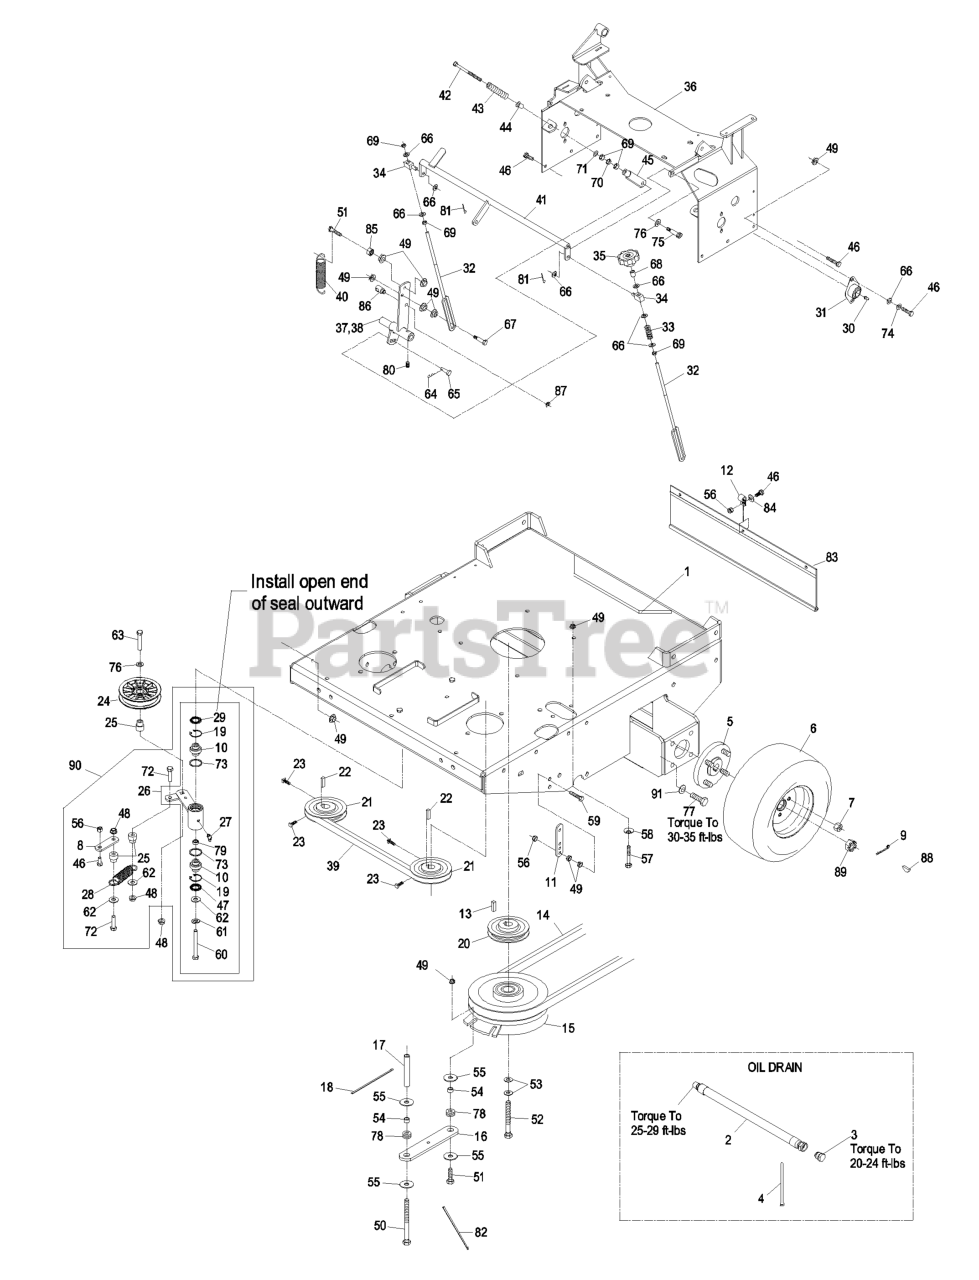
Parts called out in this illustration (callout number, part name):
4	TIE-PLASTIC
6	ASM, DRIVE TIRE
7	NUT-LUG
8	ARM-LIFT, DECK
9	PIN-COTTER
10	BEARING-SPHERICAL
11	TAB-SPRING, EXTENSION
12	CLIP-LOOM
14	BELT,DECK DRIVE
15	CLUTCH ASM
16	STRAP-CLUTCH, BRAKE
17	SPACER,SHIELD
18	TIE-CABLE
19	RING-SNAP
20	PULLEY
21	SHEAVE ASM
23	SCREW-SET
24	PULLEY-IDLER, FLAT
25	BUSHING-IDLER
26	KIT,IDLER ARM W/BRGS.
27	FITTING-GREASE, 90 DEG
28	SPRING-EXTENSION
29	SEAL-LIP, SINGLE
30	FITTING-GREASE
31	BEARING-FLANGE, SIDE
32	LINK,SPEED CONTROL
33	SPRING-COMPRESSION
35	KNOB-TRACKING
36	FUEL TANK SUPPORT
37	WLD,LH CONTROL ARM
39	BELT,COG A-59.5
40	SPRING-EXTENSION
41	WLD,CRANK SPEED CNTRL
42	BOLT-RETURN, NEUTRAL
43	SPRING-RETURN, NEUTRAL
44	BUSHING-FLANGED
45	YOKE-ADJUSTABLE
46	SCREW-HH
47	SEAL-LIP, DOUBLE
48	NUT-HHF, WHIZ
50	SCREW-HH
51	SCREW-HH
52	SCREW-HH
53	WASHER-SPRING
56	NUT-LOCK, NI
57	SCREW-HH
58	WASHER-SPRING
59	BOLT-TAP, HH
60	SCREW-HH
61	WASHER-LOCK
62	WASHER-FLAT
63	SCREW-HH
64	PIN-COTTER
65	PIN-CLEVIS
66	WASHER-PLAIN
67	SCREW-HH
69	NUT-HEX
70	NUT-JAM
71	WASHER-FLAT
72	SCREW-HH
74	WASHER-LOCK
75	SCREW-HSH
76	WASHER-FLAT
77	SCREW-HH
78	GROMMET
80	SCREW-SET
81	PIN-COTTER
82	TIE-PLASTIC
83	SHIELD,DRAG
84	WASHER-FLAT
85	NUT-JAM
86	SWIVEL-LEVER, DRIVE
87	RING-CLIP
88	KEY-WOODRUFF
89	NUT-HEX, SLOTTED
90	KIT,TT PUMP IDLER ARM
91	WASHER-BELLEVILLE
